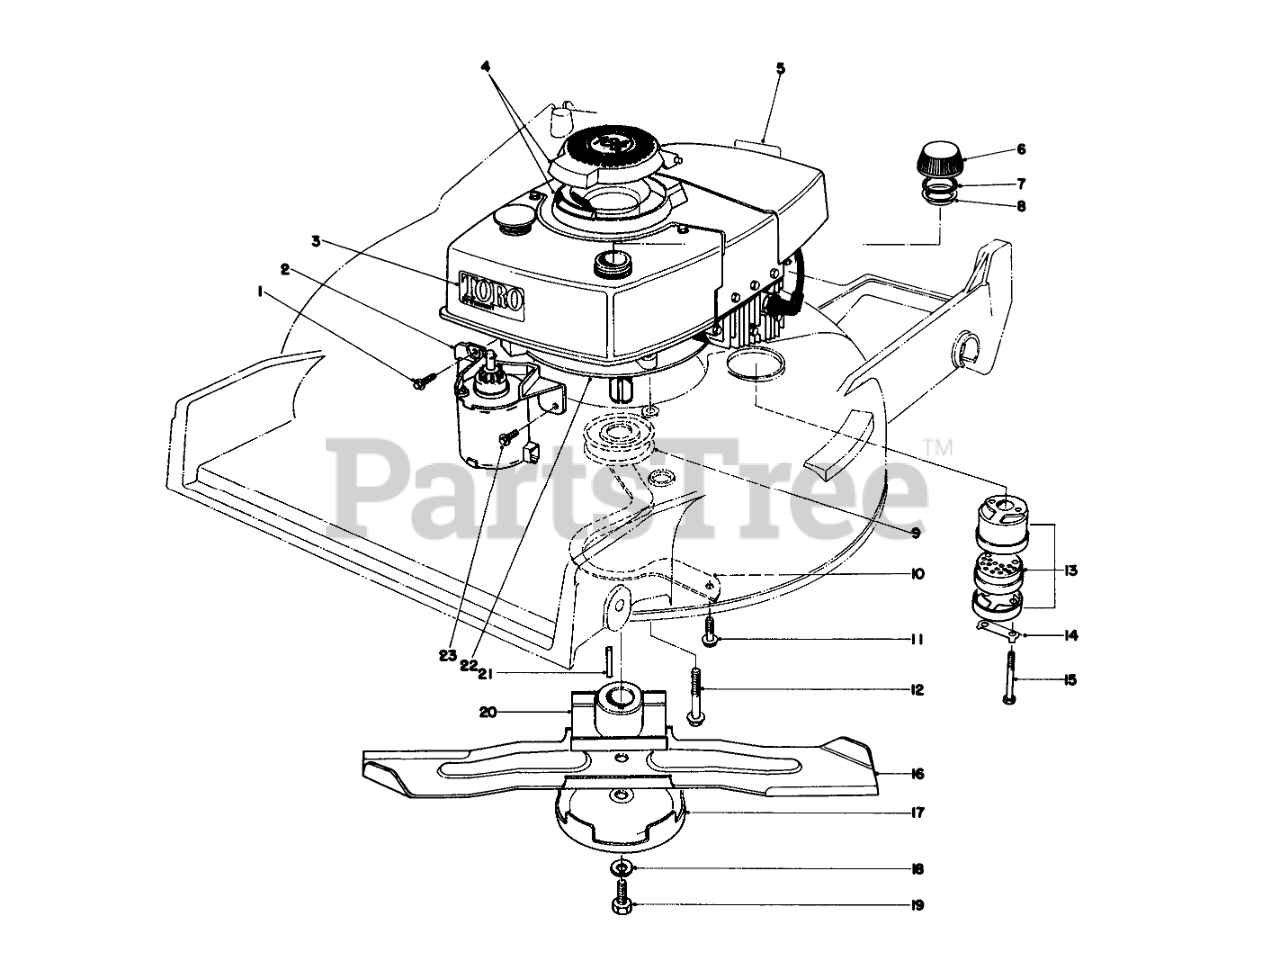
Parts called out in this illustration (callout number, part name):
1	Screw
2	Starter Motor
3	Decal
4	COVER ASM
5	Decal-Maintenan
6	Gas Cap (Incl. Ref. #7 & 8)
7	GASKET
8	GAS CAP BAFFLE
9	DRIVER PULLEY
10	BELT GUIDE
11	Screw
12	SCREW-HWHTF
13	Muffler Assembly (Incl. Ref. 14 & 15)
14	CLIP - LOCKING
15	SCREW-HH
16	Blade
17	AntiScalp Cup
18	WASHER-LOCK
19	BLADE SCREW
20	BLADE RETAINER WA(BLACK)
21	KEY-SQUARE
22	Engine
23	SCREW
